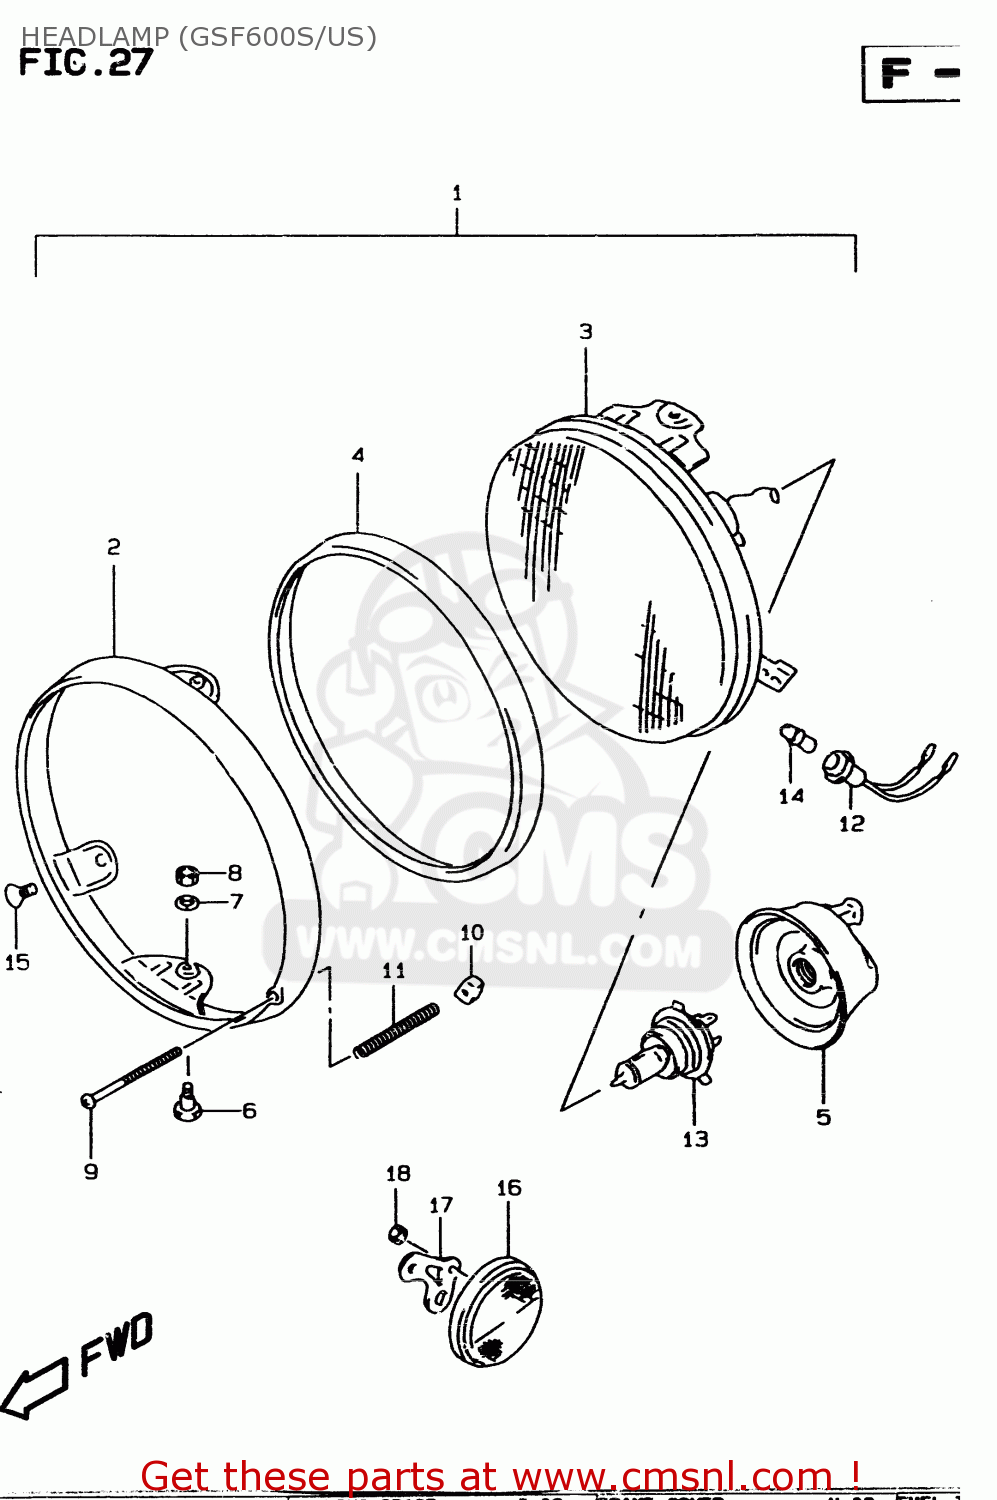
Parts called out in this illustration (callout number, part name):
1	HEADLAMP ASSY
2	RIM,HEADLAMP
3	LAMP UNIT
4	RING
5	COVER,SOCKET
6	H/LAMP LENS UNIT FITING SCRE
7	WASHER,LOCK
8	NUT
9	SCREW
10	NUT
11	SPRING,ADJUSTING
12	SOCKET,PARKING LAMP
13	BULB(12V60/55W,H4)
14	BULB(12V4W)
15	SCREW
16	REFLECTOR,REFLEX FR
17	BRACKET,FR SIDE REFLECTOR
18	NUT
